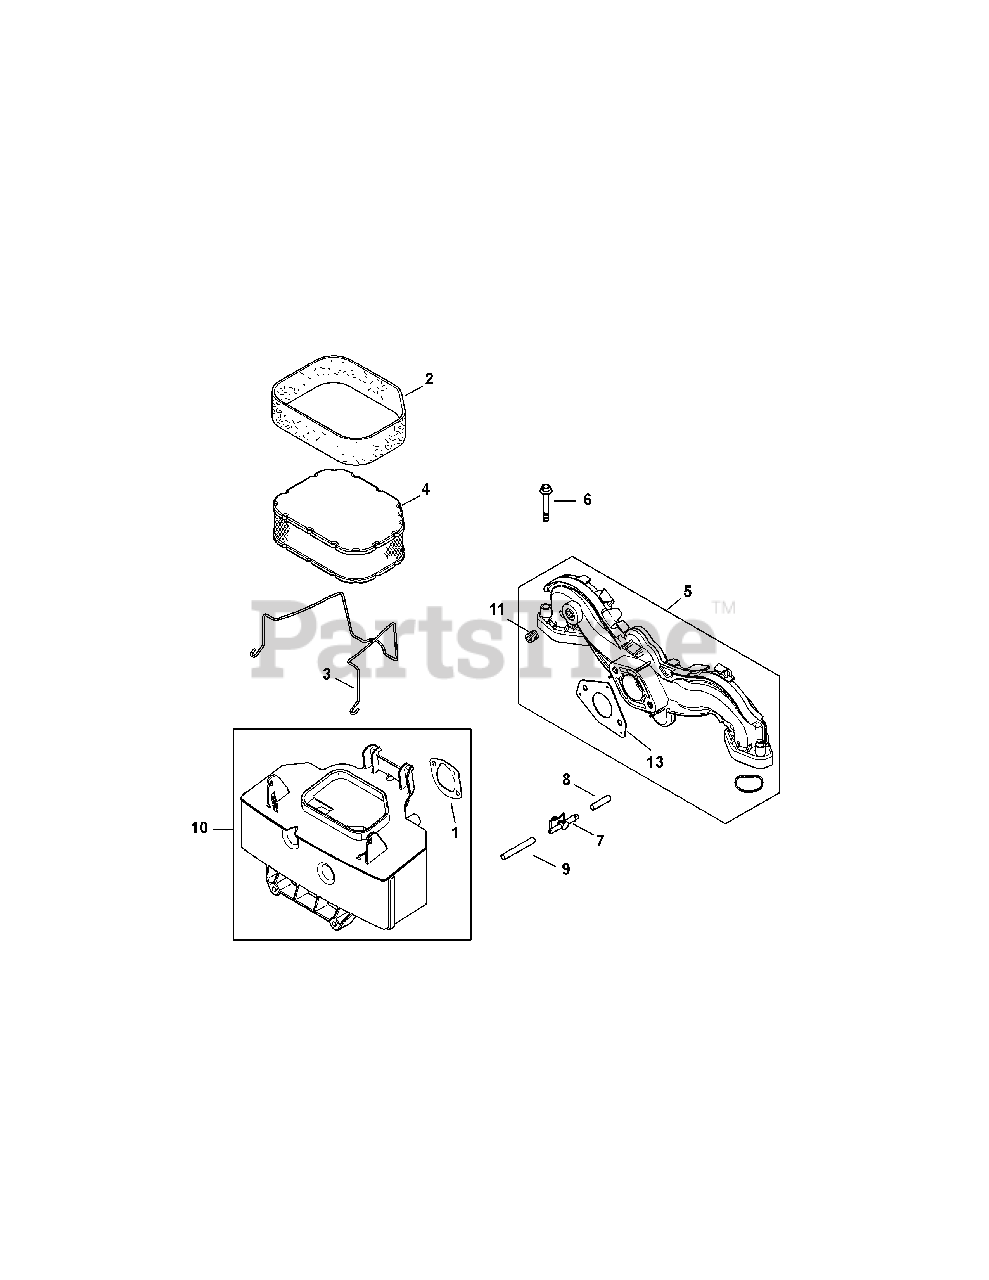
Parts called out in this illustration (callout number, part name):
1	Air Cleaner Base Gasket
2	Pre-Cleaner Element
3	Air Cleaner Element Latch
4	Air Filter Element
5	Intake Manifold Kit
6	Flange Screw, M6 x 1.0 x 40
7	Evaporative Connector
8	Evaporative Mask
9	Evaporative Hose, 20"
10	Air Cleaner Base
11	Pipe Plug, 1/8
12	Carburetor Gasket
13	Intake Port O-Ring
